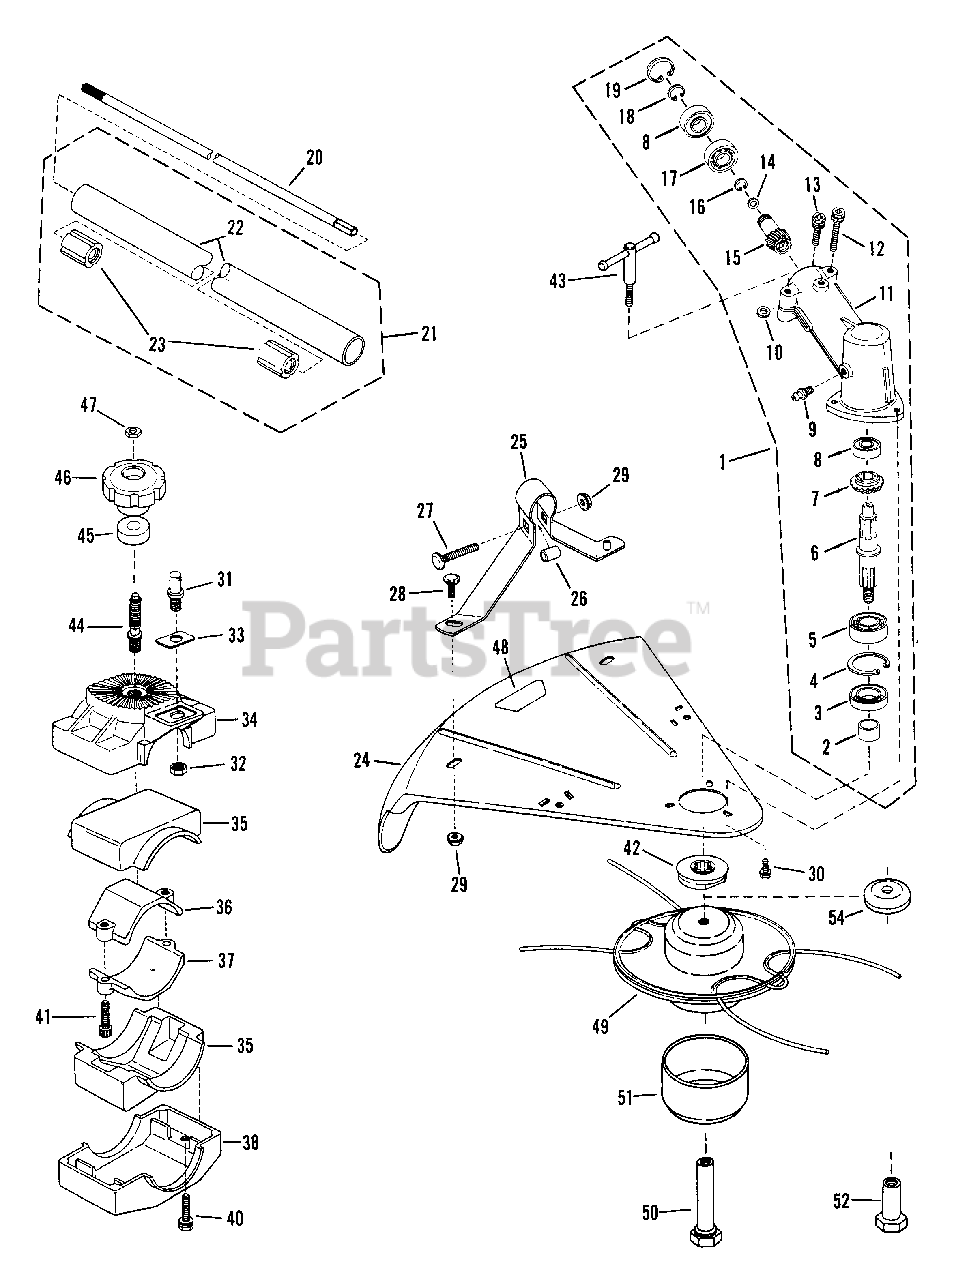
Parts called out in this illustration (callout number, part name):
1	ASSEMBLY, Gear Head
2	SLEEVE, Spline
3	SEAL, Oil
4	RING, Snap 35mm
5	BEARING
6	SHAFT, Spline
7	GEAR, Bevel
8	BEARING
9	FITTING, Lube
11	CASE, Gear
12	BOLT, M5 x 25mm Hex Head
13	BOLT, M5 x 12mm Hex Head
14	WASHER, Flat
15	PINION, Bevel
16	RING, Snap 10mm
17	BEARING
18	RING, Snap 10mm
19	RING, Snap 26mm
20	SHAFT, 1/4 Drive
21	ASSEMBLY, Tube & Bushing
22	TUBE, Main
23	BUSHING
24	SHIELD, Steel
25	BRACE, Shield
26	SPACER, 7/16 x 11/16
27	BOLT, 5/16-18 x 1-1/2 Short Neck Carriage
28	BOLT, 5/16-18 x 1/2 Short Neck Carriage
29	NUT, 5/16-18 Hex Flange Lock
30	SCREW, M5 x 10mm Hex
31	PIN, Guide
32	NUT, 3/8-24 Hex Flange Lock
33	PLATE, Mounting Pin
34	JOINT "D", Handle
35	RUBBER, Vibro
36	CLAMP "A", Tube
37	CLAMP "B", Tube
38	JOINT "C", Handle
39	JOINT "D", Handle
40	SCREW, M6 x 30mm, Cross Hex Head
41	SCREW, M5 x 20mm, Socket Hex Head
42	SPACER, Blade
43	T-BOLT, M5
44	BOLT, Latch
45	SPACER, Knob
46	KNOB, Torque
47	NUT, Self-Threader
48	LABEL, Direction
49	HEAD, Fixed Line
50	BOLT, Arbor
51	BALL, Glide
52	ARBOR, Bolt/Blade
53	NUT, M10 x 1.25 Hex Lock (Left Thread)
54	WASHER, Belleville
